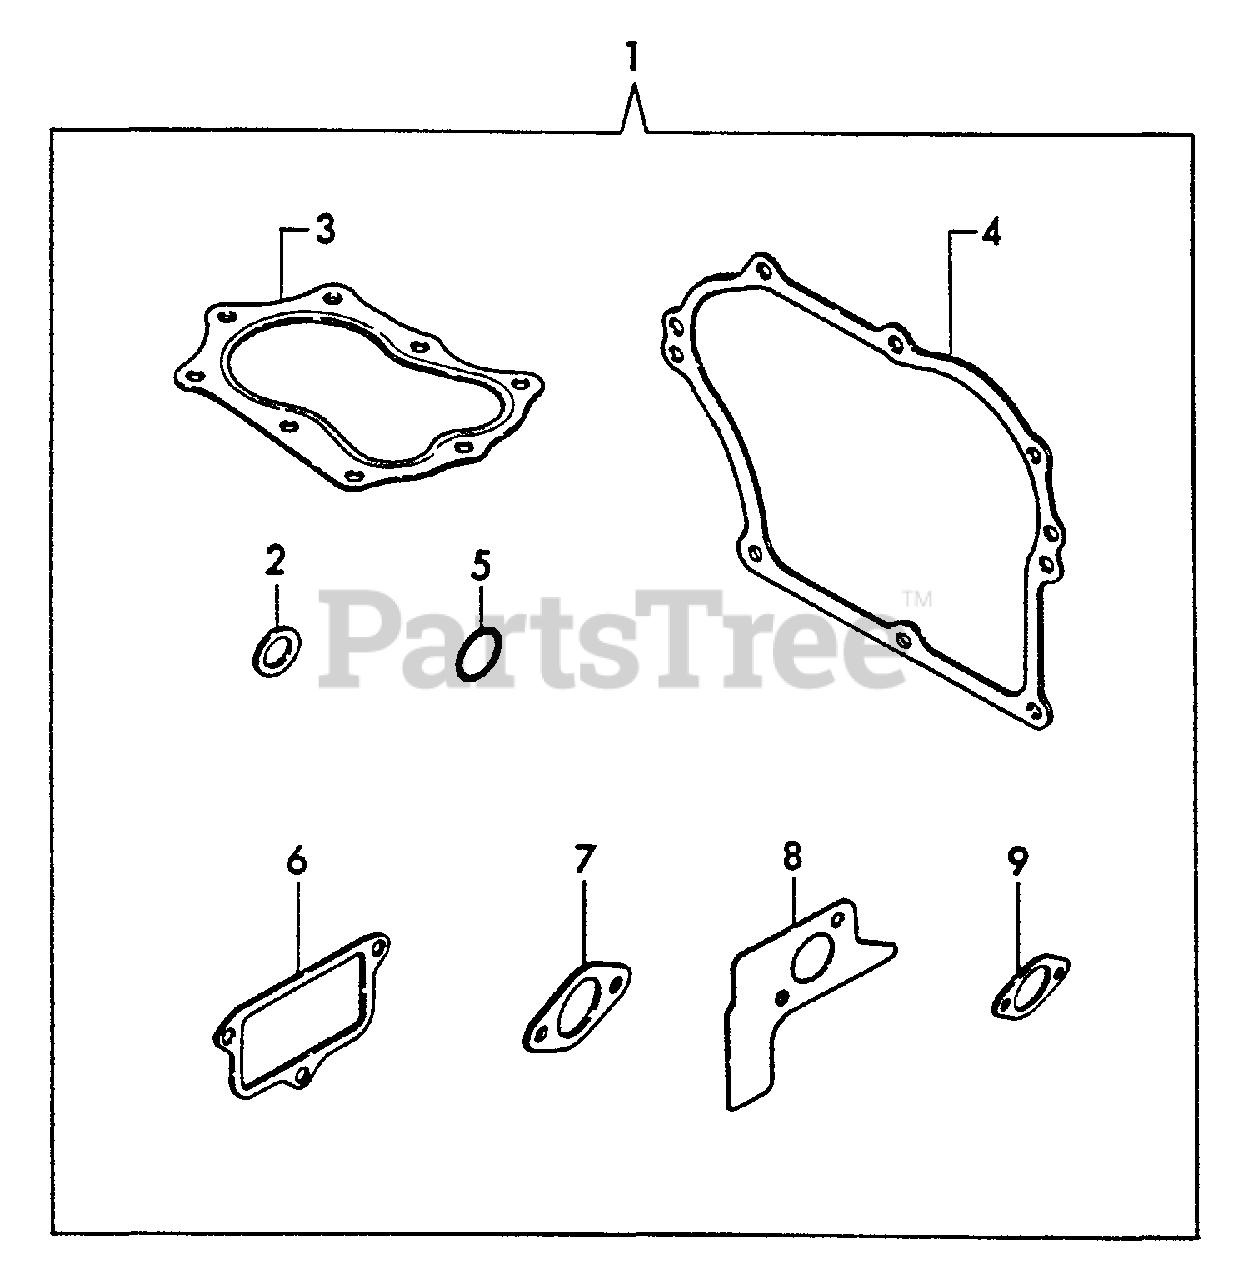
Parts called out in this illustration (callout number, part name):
1	GASKET KIT
2	GASKET
3	GASKET, CYLINDER
4	GASKET, SIDE COVER
5	O-RING - 18
6	GASKET, BREATHER
7	GASKET, INTAKE
8	GASKET, EXHAUST
9	GASKET, SPACER
